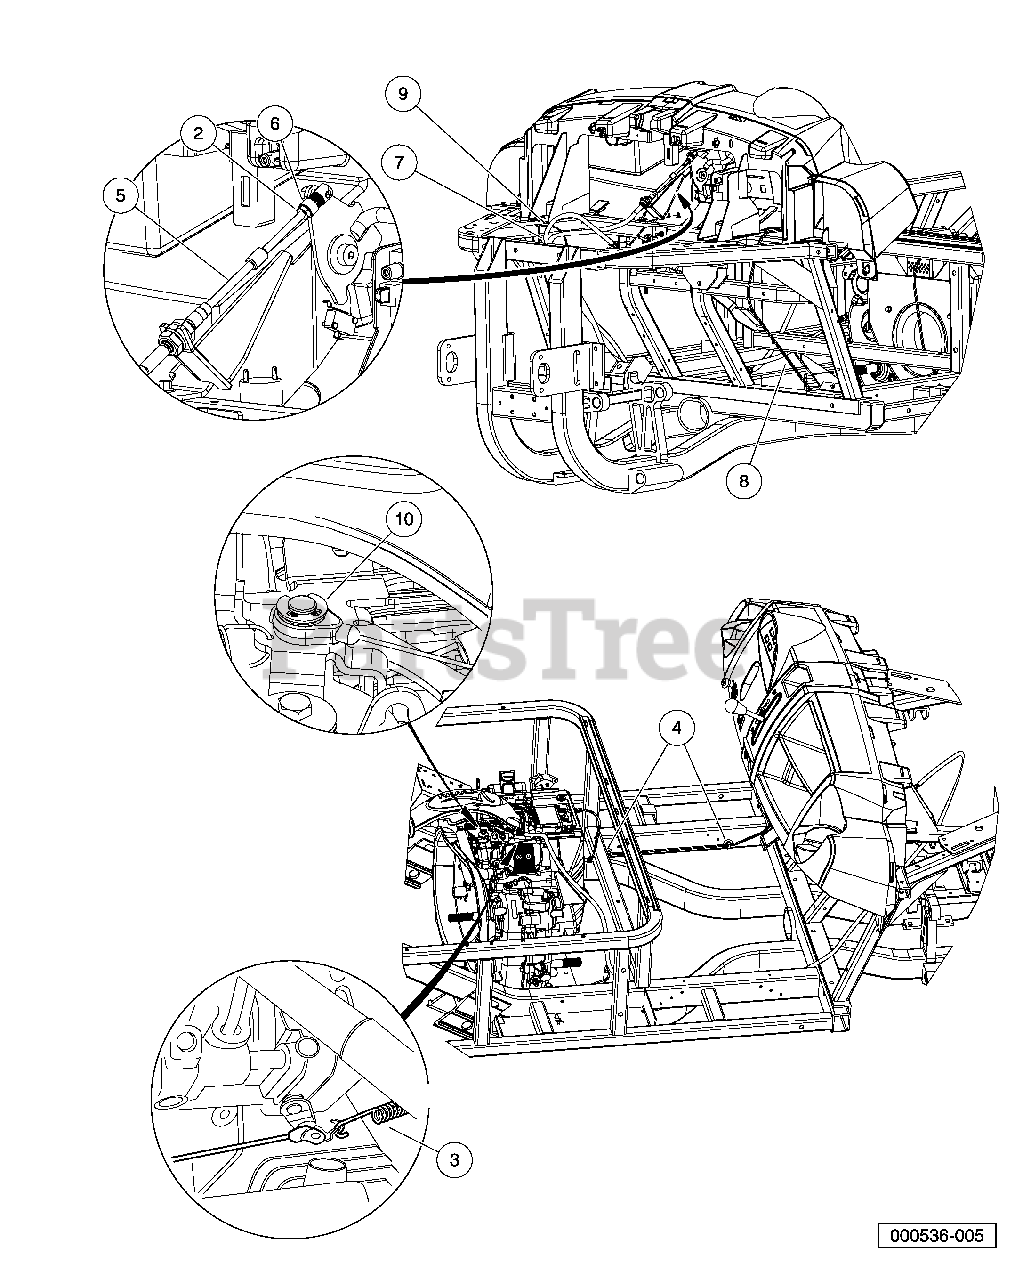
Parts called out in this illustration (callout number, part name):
1	Instl, Cable, Awd, Fh680d
2	Nut, 1/4-28 Hex Jam
4	Clip, Brake Line
5	Cable, Transmission Shift
6	Joint, Ball, .346 Dia
7	Cable, Accel, AWD, Gas, FH680D
8	Cable, Choke, AWD, FH680D
9	Tie Wrap, 8" Nylon
10	Ring, Retaining
